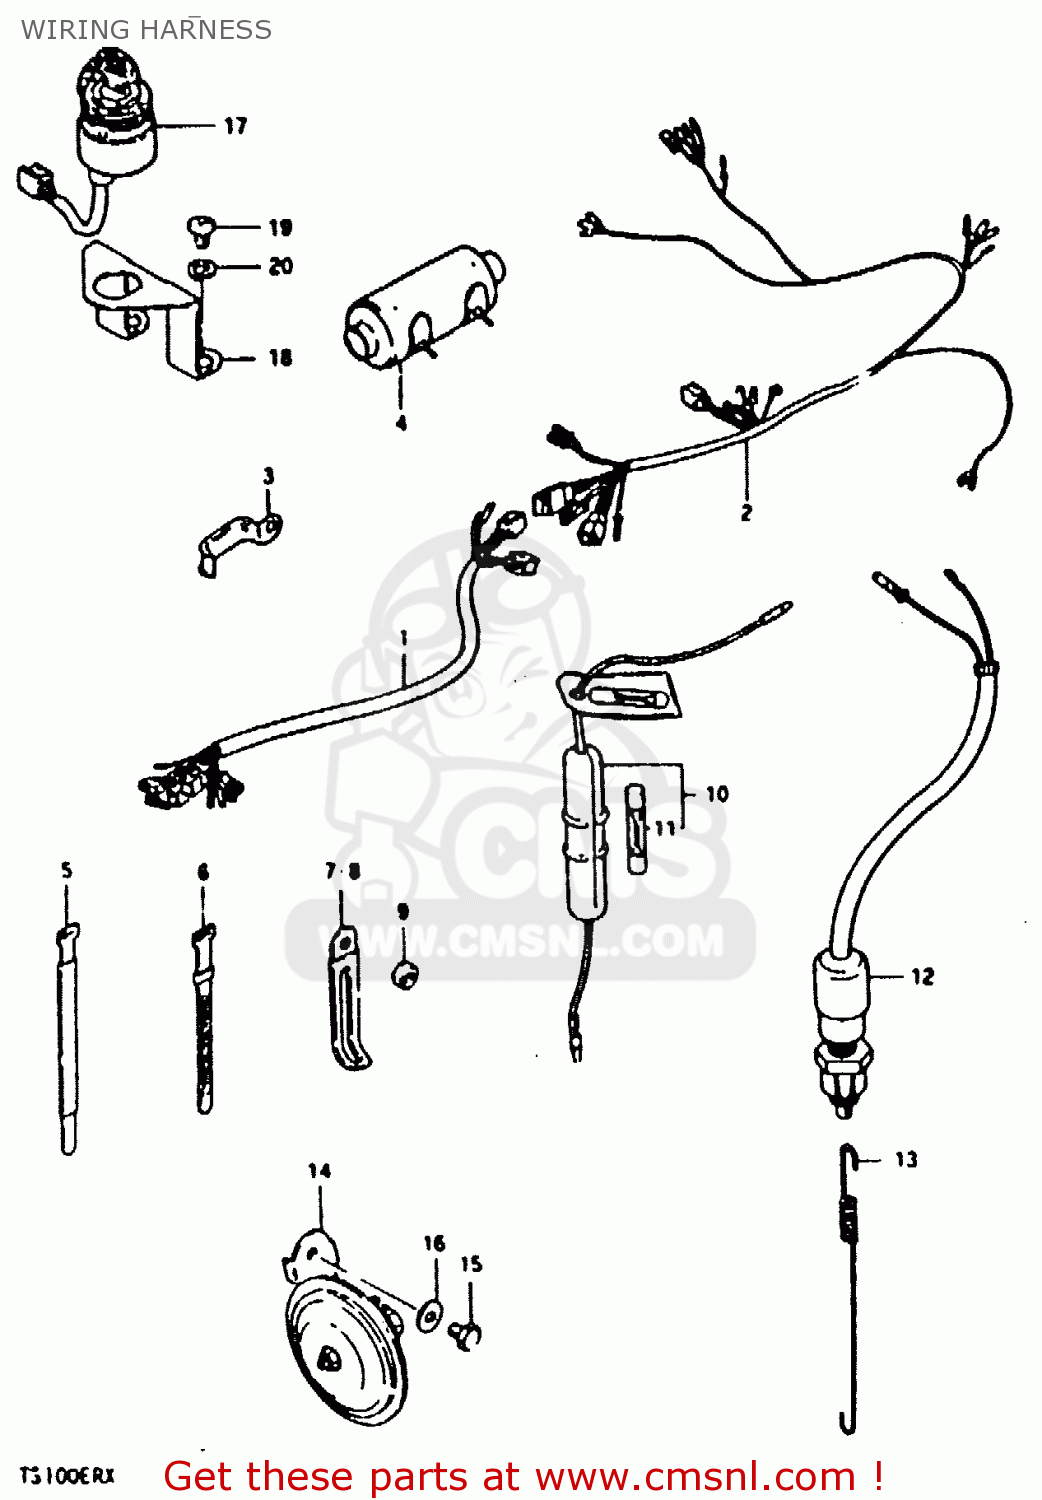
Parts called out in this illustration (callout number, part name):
1	WIRING HARNESS NO.1
2	WIRING HARNESS NO.2
3	CLAMP
4	BOOT,WIRING HARNESS
5	CLAMP
6	CLAMP(L:120)
7	CLAMP
8	CLAMP
9	NUT
10	BOX ASSEMBLY,FUSE
11	FUSE(10A)
12	SWITCH ASSEMBLY,STOP LAMP
13	SPRING
14	HORN ASSEMBLY
15	BOLT
16	WASHER
17	SWITCH ASSY, IGNITION
18	BRACKET,IGNITION SWITCH
19	SCREW
20	LOCK WASHER
